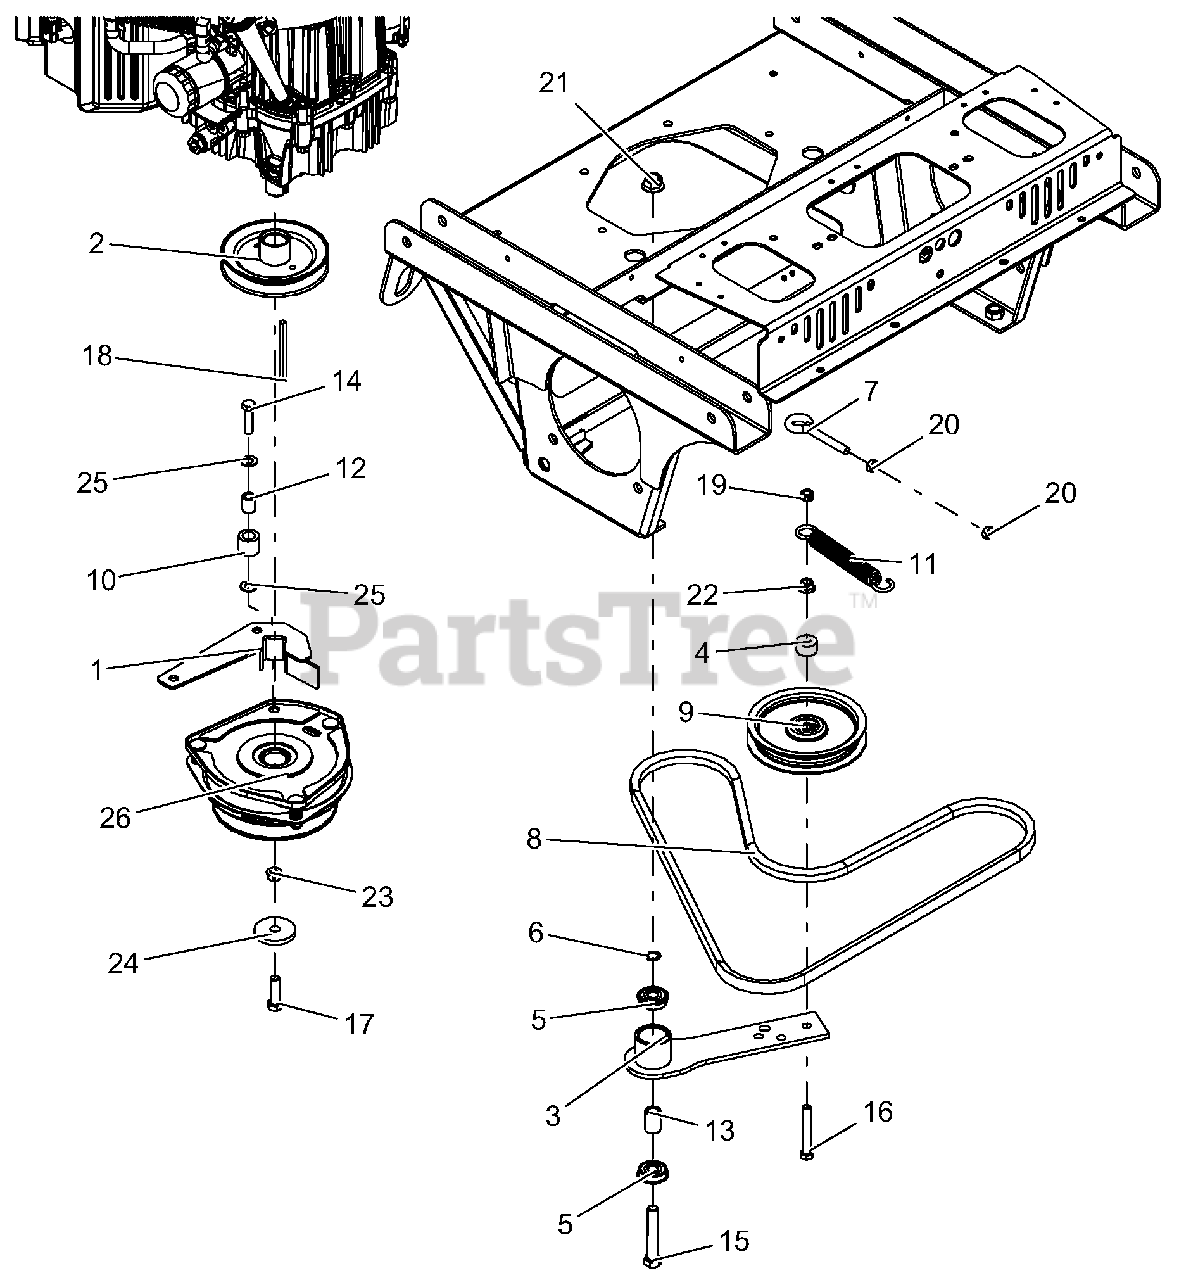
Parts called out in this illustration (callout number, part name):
1	WMT, CLUTCH STOP - BLACK
2	SHEAVE, ENGINE 1.127 ID X 5.250 OD-BLACK
3	WLDMT, HYDRO DRIVE IDLER ARM-BLACK
4	SPACER .390X1.000X.562
5	BRG, BALL .501 X 1.38 X .438 SEALED
6	WASHER-FLAT-STL, .500 X .750 X .020
7	BOLT, EYE .375-16
8	BELT, B RAW COGGED
9	IDLER, FLAT 5.00 X 3.8
10	BUMPER, RUBBER .62 X 1.0 X .88 LG
11	SPRG, EXTENSION
12	BUSHING, SLV .407X.625X.813
13	SPACER, .510 X .750 X 1.148
14	BLT-HEX .38-16X1.50 GR5 YWZC
15	BLT-HEX .50-13X3.00 GR5 YWZC
16	BLT-HEX .38-16X2.75 GR5 YWZC
17	BLT-HEX .44-20X1.50 GR8 YWZC
18	KEY-SQ .250X.250X3.50
19	NUT-LK-CTR .38-16 YWZC
20	NUT, JAM .375-16 YWZC
21	NUT-LK-NYL-FLG .50-13 YWZC
22	NUT-LK-NYL-FLG .38-16 YWZC
23	NUT, LK-TOP-FLG .38-16 YWZC
24	WSHR-FL-STL .469X2.00X.25 YWZC
25	WSHR-FL-STL.406X.812X.065 YWZ
26	CLUTCH-OGURA
